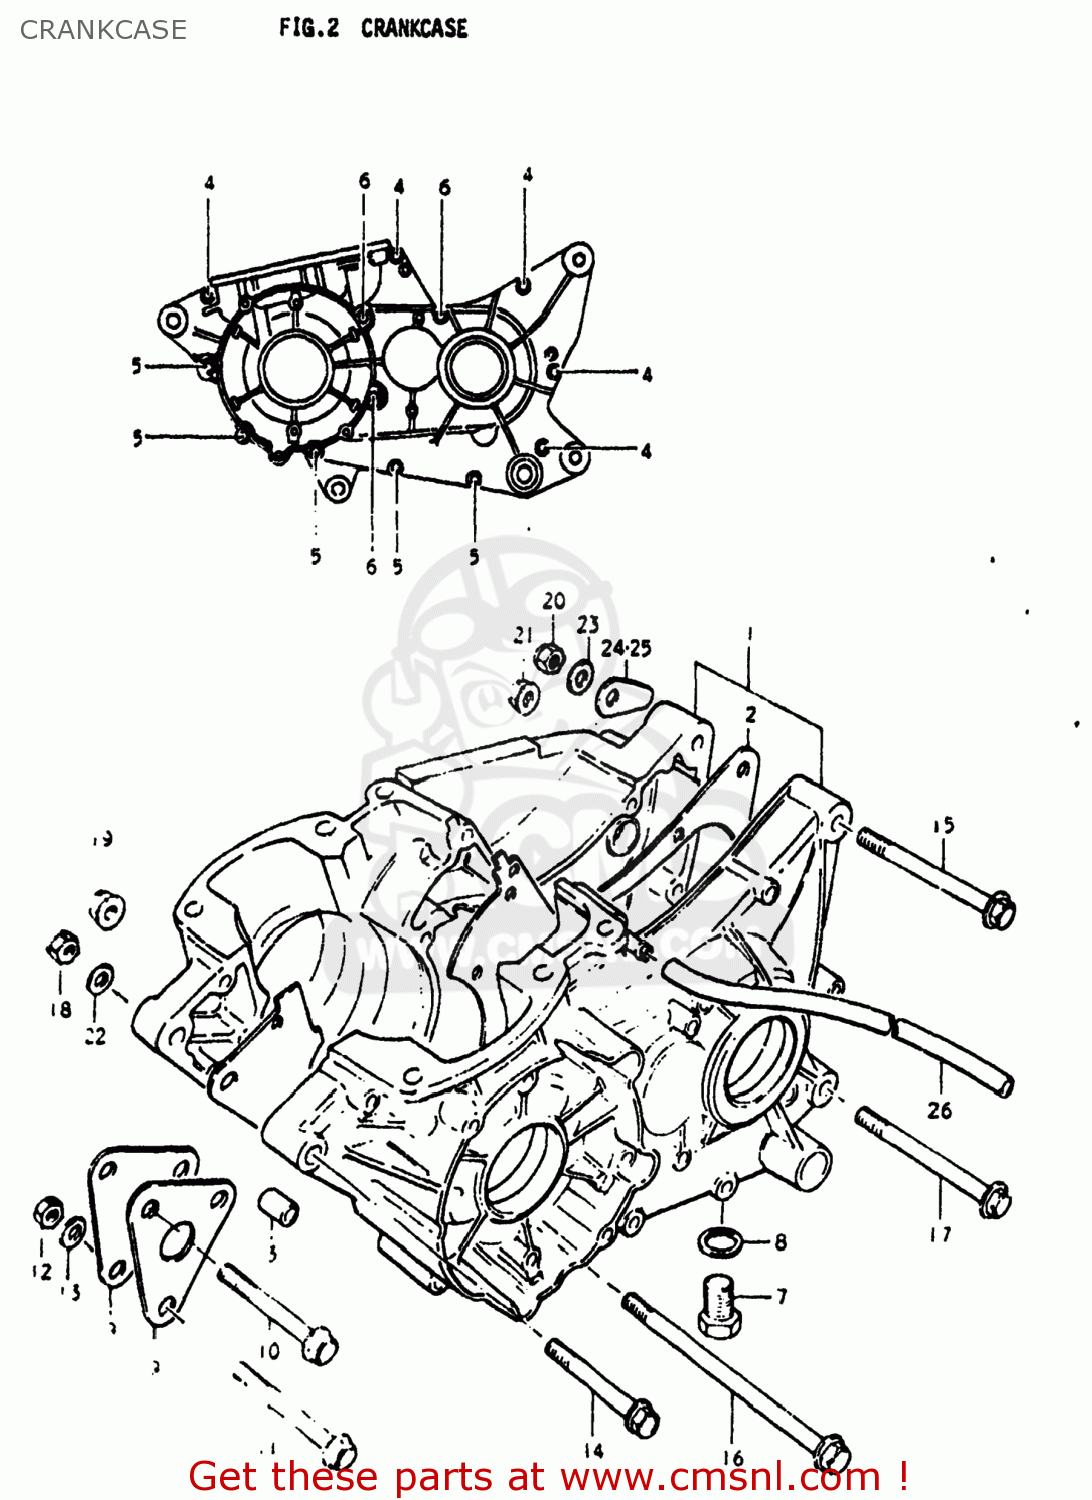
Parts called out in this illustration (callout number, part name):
1	CRANKCASE SET
2	GASKET,CRANKCASE (MCA)
3	PIN
4	SCREW (6X45)
5	SCREW
6	SCREW 6X70
7	PLUG
8	GASKET(14X19.2X2) (NAS)
9	PLATE,ENGINE MOUNTING
10	BOLT
11	BOLT
12	NUT
13	WASHER
14	BOLT
15	BOLT
16	BOLT
17	BOLT(8X80)
18	NUT
19	NUT
20	NUT
21	NUT
22	WASHER
23	WASHER
24	WASHER
25	WASHER
26	HOSE
